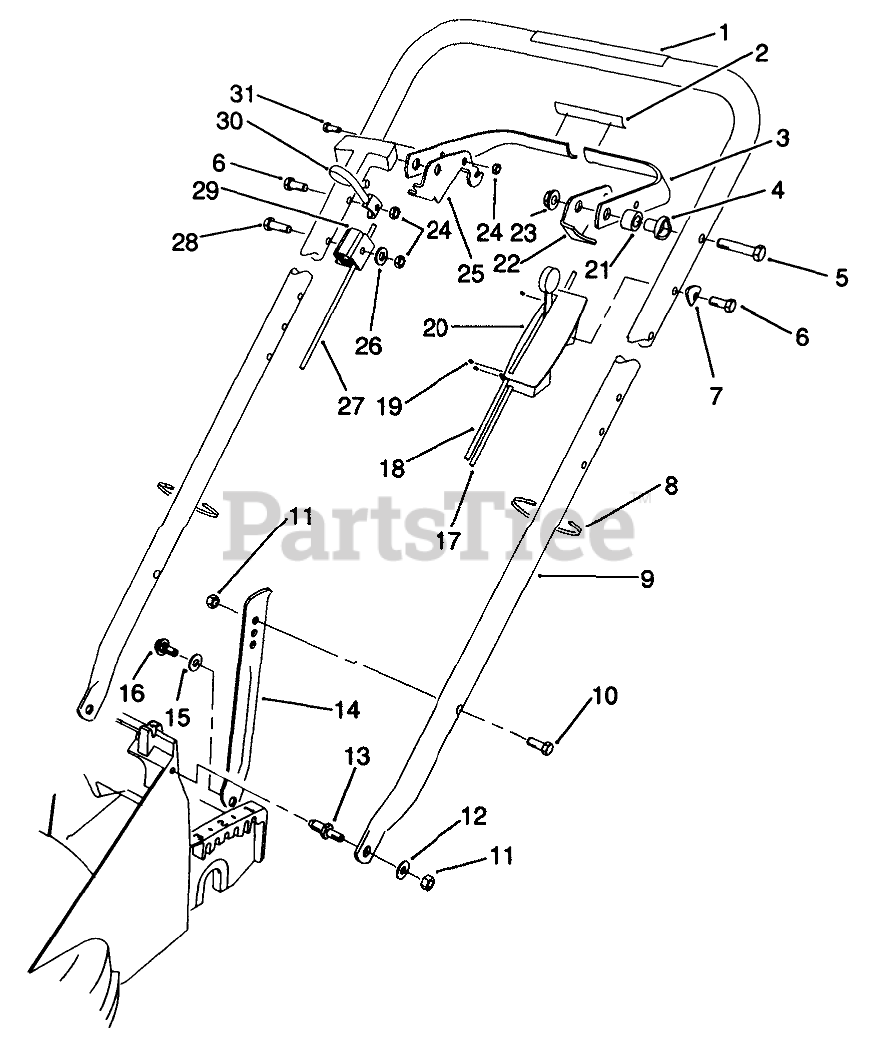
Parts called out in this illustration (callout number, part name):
1	DECAL - WARNING/INSTR
2	DECAL-TRACTION CONTROL
3	Bar-Control
4	SPACER-SUPPORT
5	SCREW-HH
6	SCREW-HH
7	WASHER
8	TIE-CABLE
9	HANDLE W/DECAL (R&S)
10	SCREW-HH
11	NUT-LOCK, NI
12	WASHER-PLAIN
13	SHOULDER STUD SCREW
14	HANDLE LATCH B
15	NYLON WASHER
16	SCREW-SHOULDER
17	Cable-Traction
18	CABLE-THROTTLE
19	E-RING
20	Bracket-Throttle
21	SPACER-NYLON
22	LEVER-CONTROL
23	NUT-LOCK, NI
24	NUT-LOCK, NI
25	Control Lever
26	WASHER-FLAT
27	BRAKE CABLE
28	SCREW-HH
29	SUPPORT-CABLE
30	GUIDE-ROPE
31	SCREW-HH
